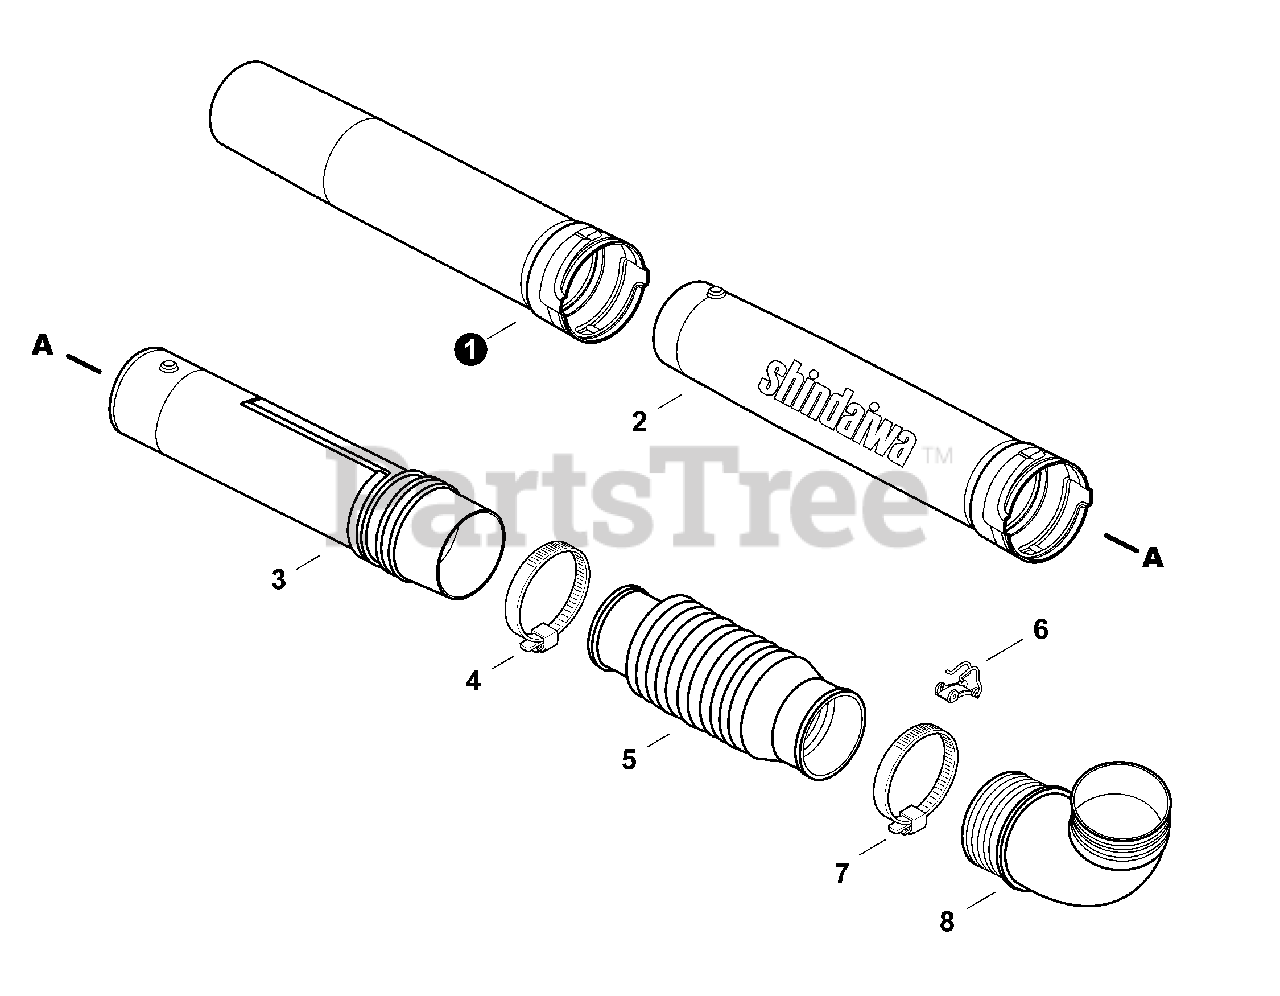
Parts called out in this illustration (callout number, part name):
1	TUBE, BLOWER - NOZZLE
2	TUBE, BLOWER - STRAIGHT
3	TUBE, BLOWER - SWIVEL
4	CLAMP 58.7 MM / 82.5 MM
5	TUBE, BLOWER - FLEXIBLE
6	CLIP, CABLE
7	CLAMP - BAND
8	TUBE, BLOWER - ELBOW
